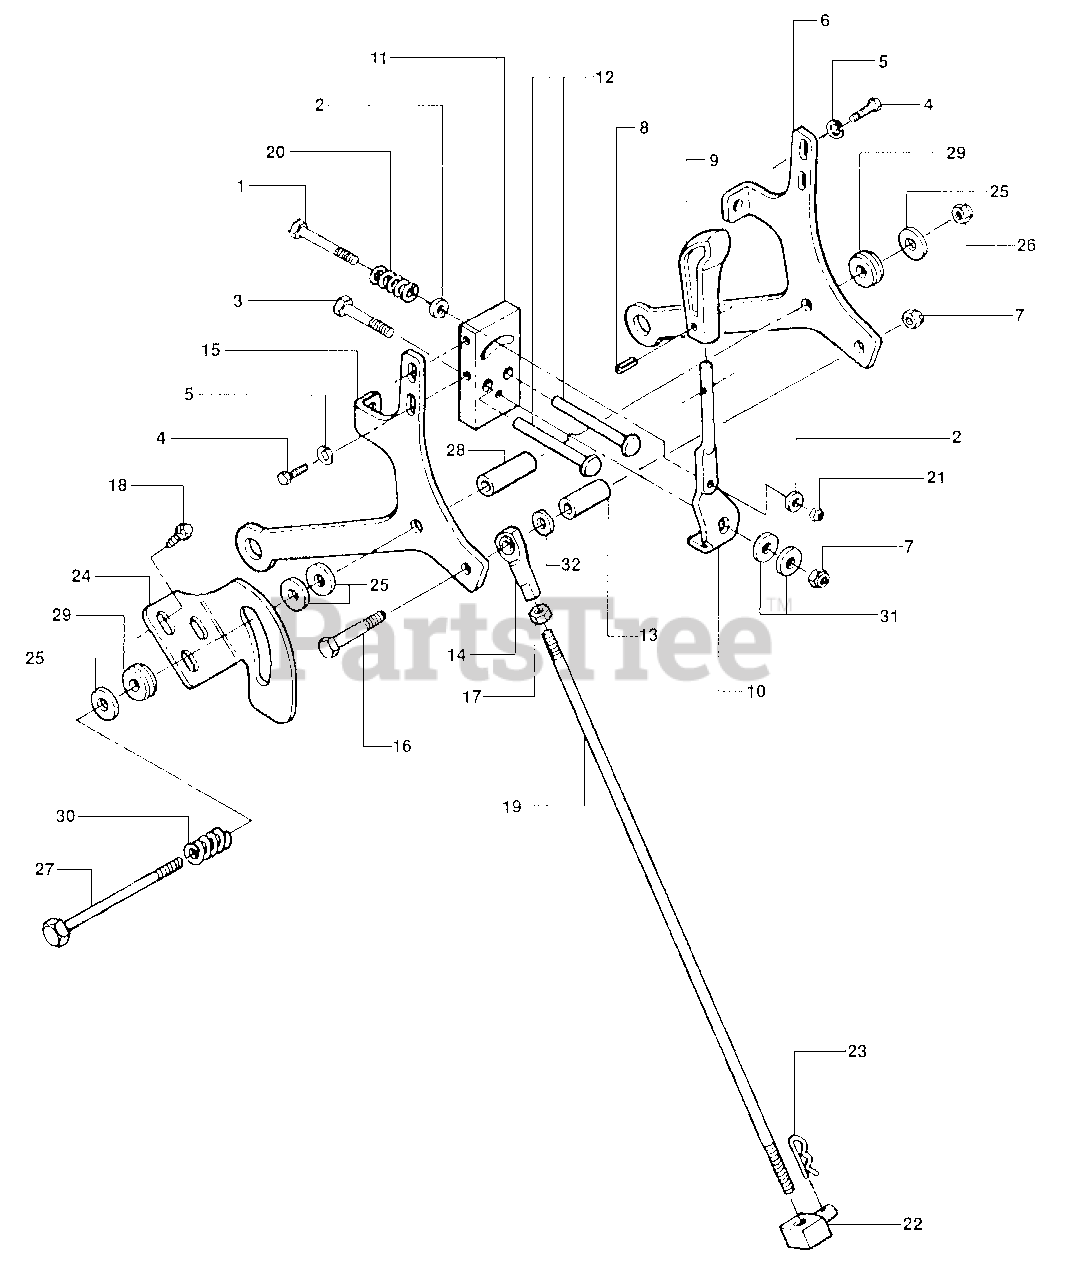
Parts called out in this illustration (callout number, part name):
1	BOLT, 1/4-20 x 2 1/2"
2	WASHER, 1/4"
3	BOLT, 5/16-18 x 2"
4	SCREW, 1/4-20 x 5/8"
5	WASHER, 1/4" Split Lock
6	TRACKING CONTROL ARM (Left Side)
7	NUT, 5/16 Nyloc
8	PIN, 3/16 x 1" Roll
9	HANDLE
10	WELDMENT, Speed Control
11	BLOCK, Tracking Control
12	PIN, Speed Control
13	SPACER, 1 3/16"
14	LINKAGE, 5/16
15	TRACKING CONTROL ARM (Right Side)
16	BOLT, 5/16-18 x 2-1/2"
17	NUT, 5/16-24 Hex
18	SCREW, 1/4-20 x 1/2" Self-Tapping
19	ROD, Speed Control
20	SPRING, Tracking Control
21	NUT, 1/4" Nyloc
22	SWIVEL
23	HAIR-PIN
24	BRACKET, Speed Control (Right Side)
25	WASHER, 3/8" Flat
26	NUT, 3/8 Nyloc
27	SCREW, 3/8-16 x 5"
28	SPACER, 1 3/4"
29	WASHER, Nylon
30	SPRING
31	WASHER, 5/16
32	WASHER, 5/16
